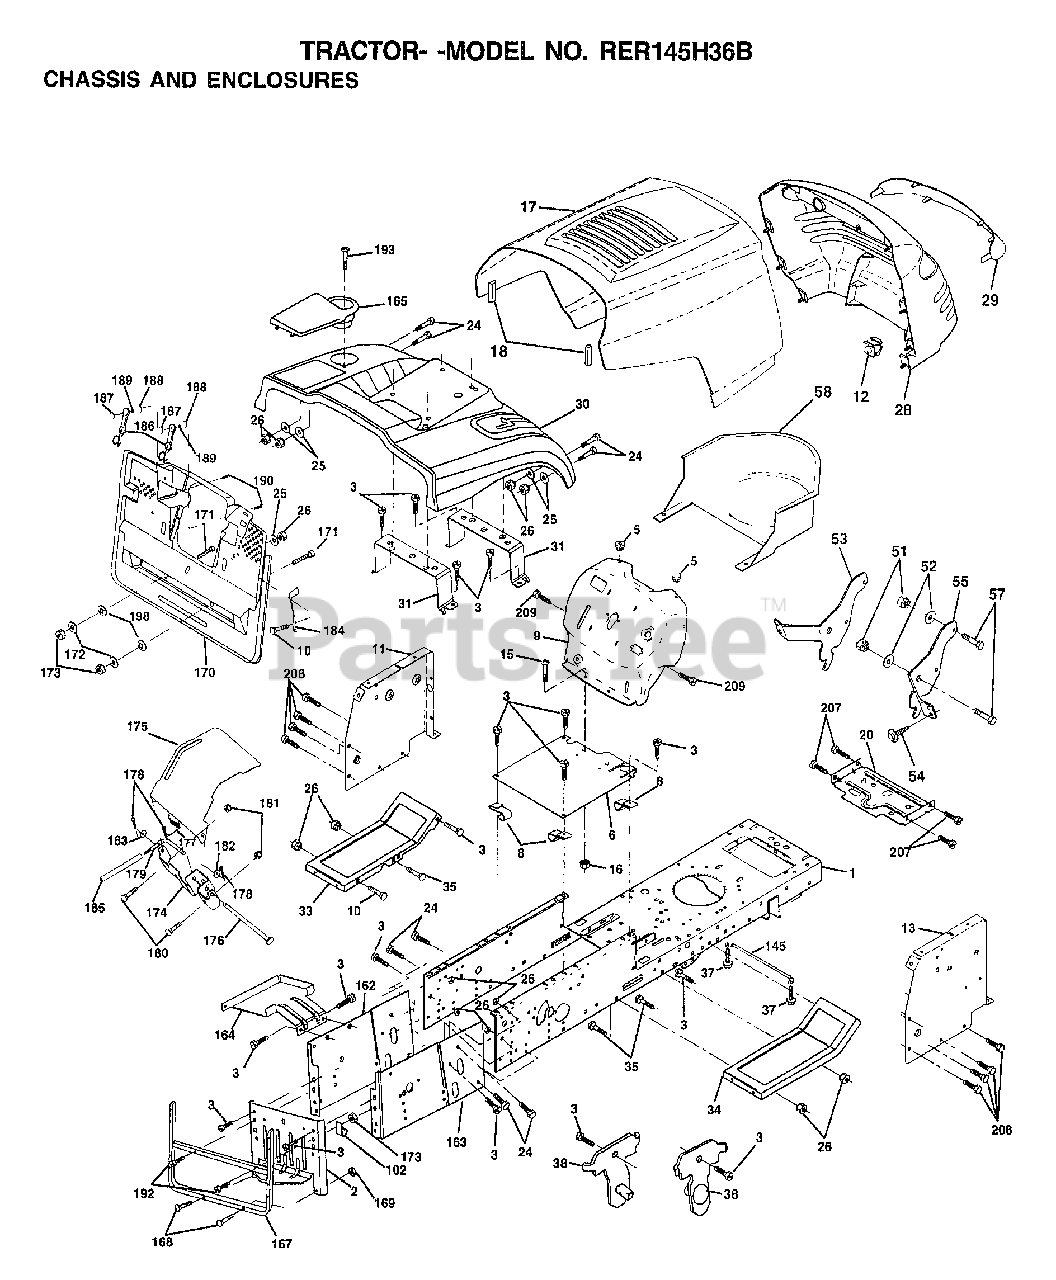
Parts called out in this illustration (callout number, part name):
2	DRAWBAR.CRD
3	SCREW
5	BUMPER-HOOD/DASH
6	SADDLE
8	"CLIP,INSULATOR"
9	DASH
11	"PANEL-DASH,LH"
12	CLIP.TINNERMAN
15	SCREW
17	HOOD.STEEL.ASSY
20	"PLATE-MTG,BATT/FU"
24	BOLT
25	WASHER
26	NUT
28	GRILLE-MS428
29	LENS.GRILLE.PRIVATE LABEL
31	BRKT.SUPT.FENDER.CRD
33	FOOTREST LH
34	FOOTREST RH
35	BOLT
37	SCREW LT
38	BRKT ASM PIVOT MOWER REAR
51	NUT
52	WASHER
53	BRACKET.GRILLE.LH
54	SCREW.HEX.WS.HD
55	BRACKET.GRILLE.RH
58	AIR DUCT
102	CLIP T
145	"ROD POVOT,CHASSIS"
162	BRKT.EXT.CHASSIS.LH.CRD
163	BRKT.EXT.CHASSIS.RH.CRD
164	SUPPORT.BATTERY.CRD
165	COVER.BATTERY.CRD.BLACK.LT
167	SUPT.ASM.BACKPLATE
168	BOLT-RD HD SQ NK
170	COVER.BACKPLATE.BLACK
171	BOLT.HEX.3/8-16X2-1/2
173	NUT
174	BRKT.SWITCH.FBI.CRD
175	GRUARD.DOOR.REAR.CRD
176	HINGE PIN
177	SPRING.COVER.LH
179	ROD.PIVOT.FBI.CRD
182	WASHER.385X.625
183	WASHER
184	BRKT.ACTUATOR.BAG.CRD
185	TUBE.LEVER.SWCH.FBI.CRD
186	LATCH ASSY.BAGGER
187	WELDNUT
188	WASHER #10
189	LOCKWASHER
190	SCREW
192	SCREW LT
193	SCREW
198	NUT PUSH
207	SCREW
208	SCREW
209	SCREW
